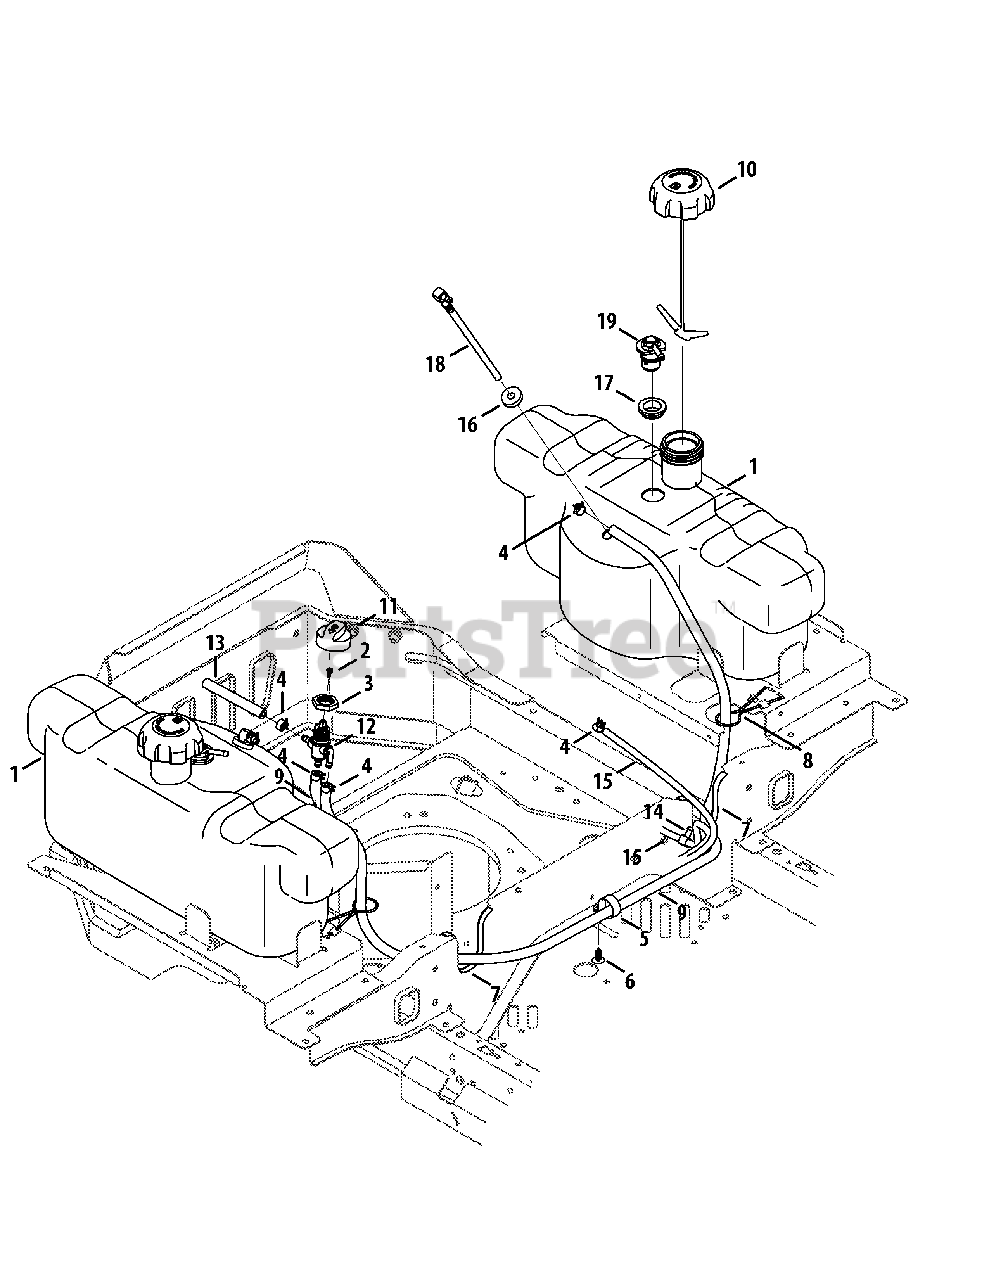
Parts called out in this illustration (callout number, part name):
1	Fuel Tank
2	Screw, M4-0.7 x 8mm
3	Nut, 3 Way Select
4	Hose Clamp, .490 Dia.
5	Hose Clamp, 1.0
6	Ratchet Clip, .250
7	Trim Strip
8	Tank Support Rod
9	Fuel Hose, Low Permeation, 1/4
10	Fuel Cap
11	Fuel Cap, 3 Way
12	Fuel Switch
13	Fuel Hose, Low Permeation, 1/4
14	Tee Fitting
16	Fuel Tank Bushing
17	Rubber Grommet
18	Fuel Pickup Fitting
19	Rollover Valve
